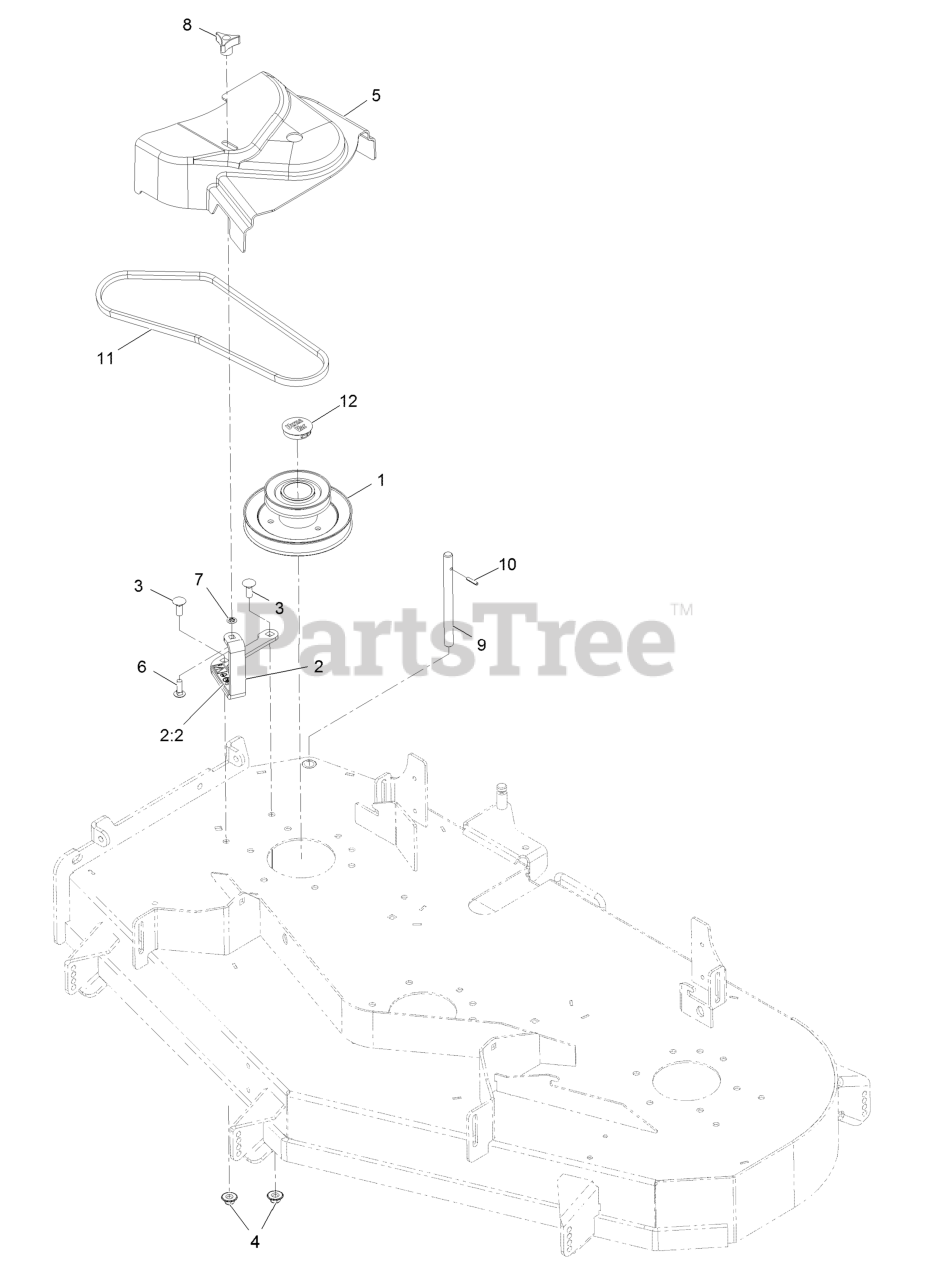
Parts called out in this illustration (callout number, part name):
1	JACKSHAFT-UV DRIVE 523
2	ASM-CVR BRKT W/DECAL
2:2	DECAL-DANGER
3	BOLT-CARR
4	Nut-Nyloc 3/8-16 Flg
5	COVER-BELT, UV 52
6	BOLT-CARR
7	RING-RETAINING, BOLT
8	KNOB-3 PRONG
9	SHAFT-CATCHER, GRASS
10	PIN-ROLL
11	BELT, BLOWER 52"DECK
12	PLUG, BLACK NYLON 1.75
